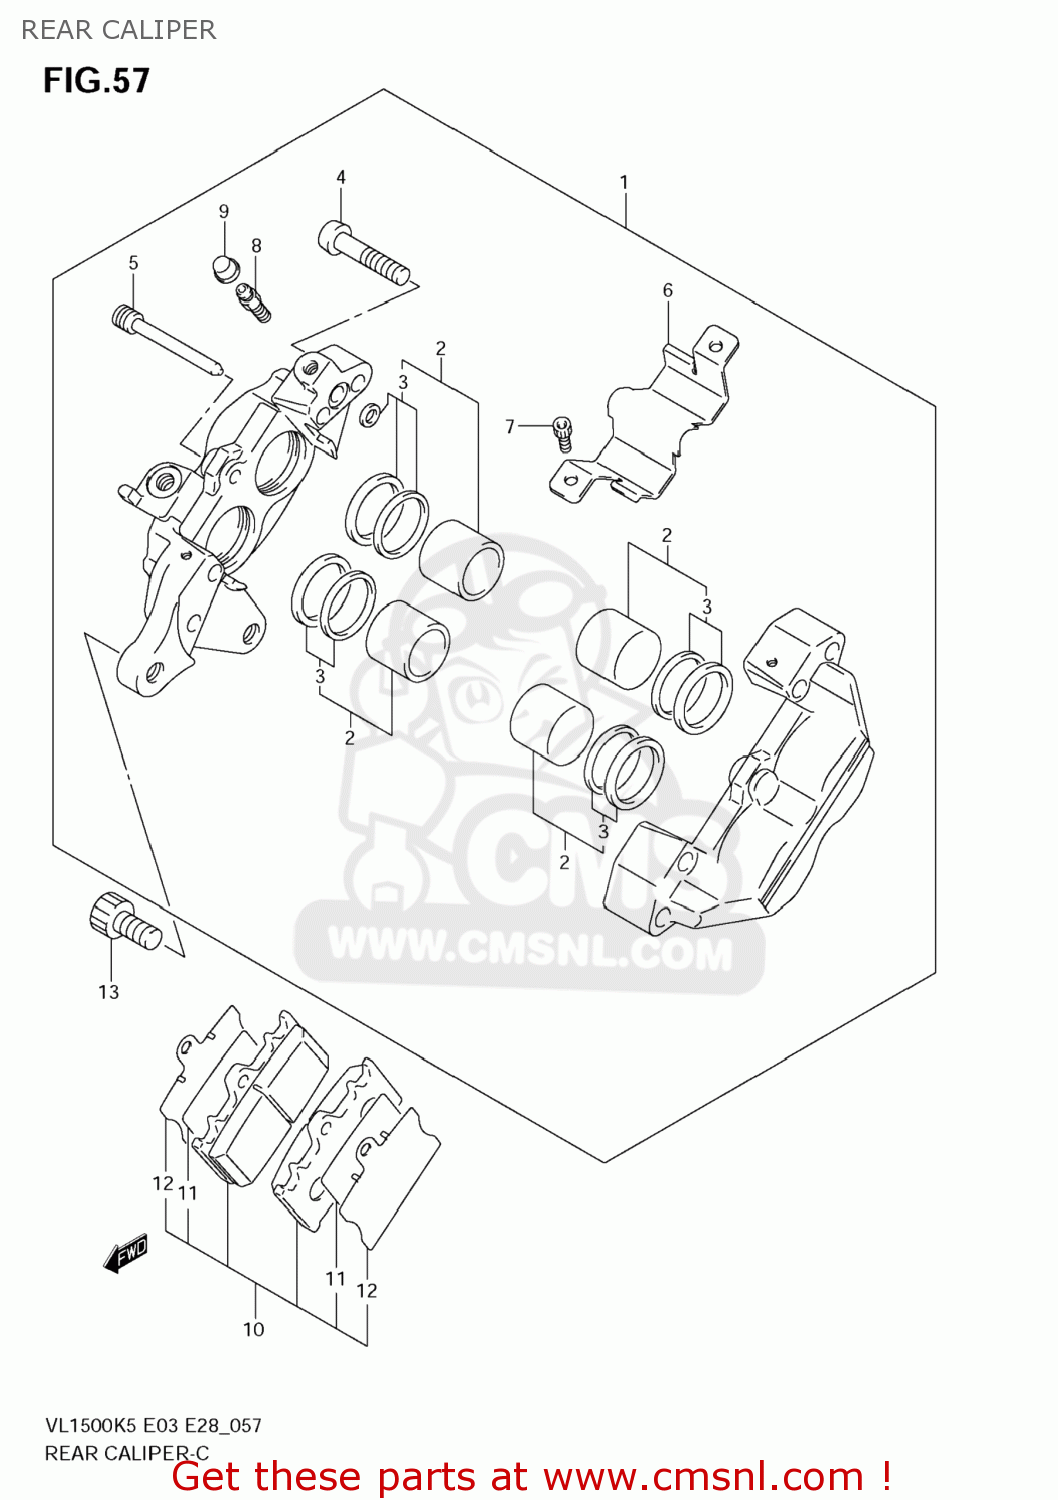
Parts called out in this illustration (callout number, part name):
1	CALIPER ASSY,RR
2	PISTON SET
3	SEAL SET,PISTON
4	BOLT
5	PIN,PAD
6	COVER
7	SCREW
8	BLEEDER
9	CAP,BLEEDER PLUG
10	PAD & SHIM SET (NAS)
11	SHIM,PAD
12	COVER,SHIM
13	BOLT
